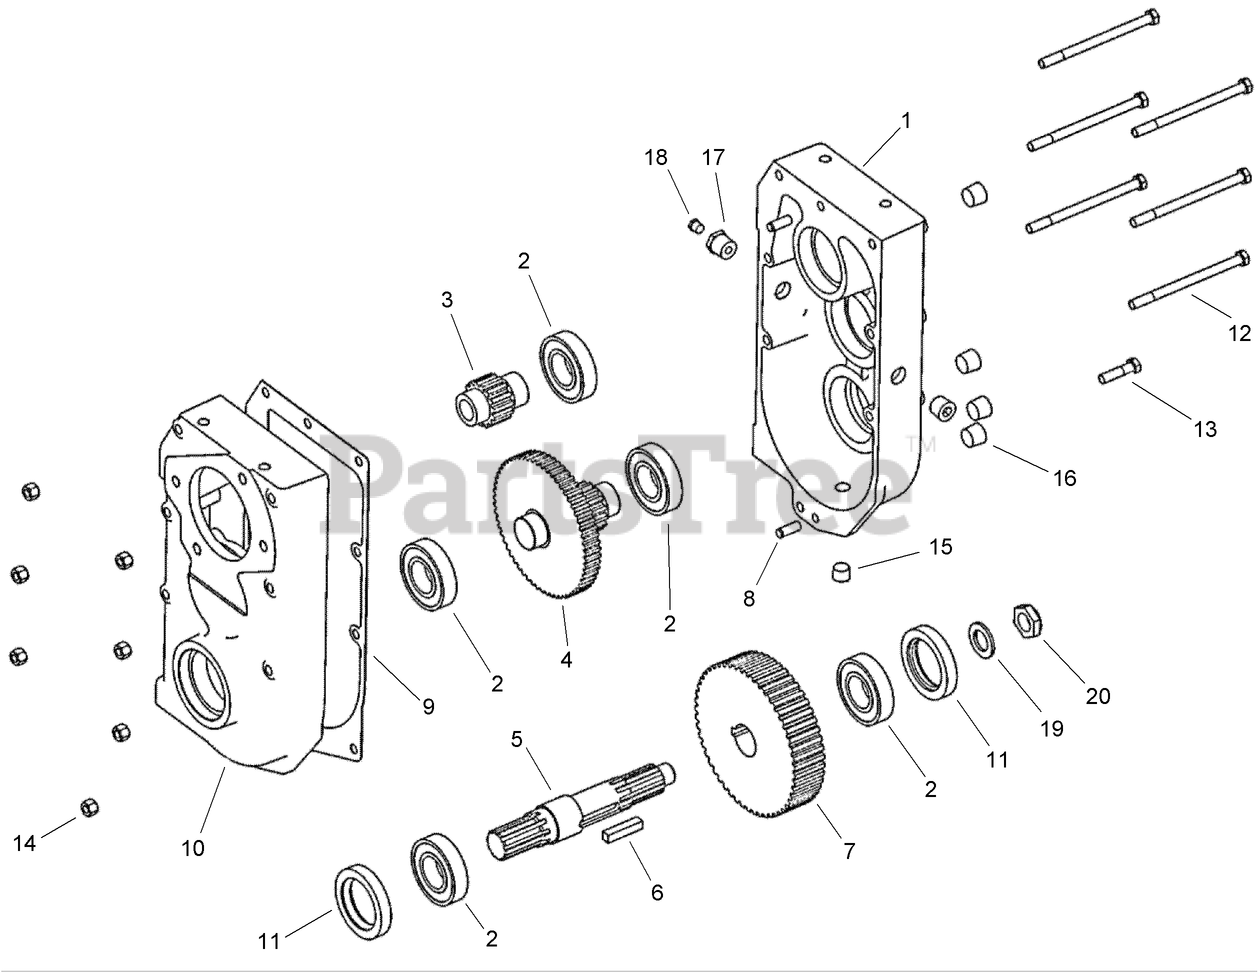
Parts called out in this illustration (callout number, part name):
1	CASE-GEAR
2	BEARING
3	GEAR-MOTOR, 18 TEETH
4	GEAR-CLUSTER, 59/15 TEETH
5	SHAFT-OUTPUT
6	KEY-SQUARE
7	GEAR-REDUCTION, 51 TEETH
8	PIN-DOWEL
10	CASE-GEAR
11	SEAL-OIL
12	SCREW-HH
13	BOLT-hex, 3/8 NC x 1-1/2 inch
14	NUT
15	PLUG-HEX SOCKET, PIPE
16	PLUG-PIPE, HEX SOCKET
17	FITTING-STRAIGHT
20	NUT - Jam, Hex, 7/8 - 14 NF, Nyloc
